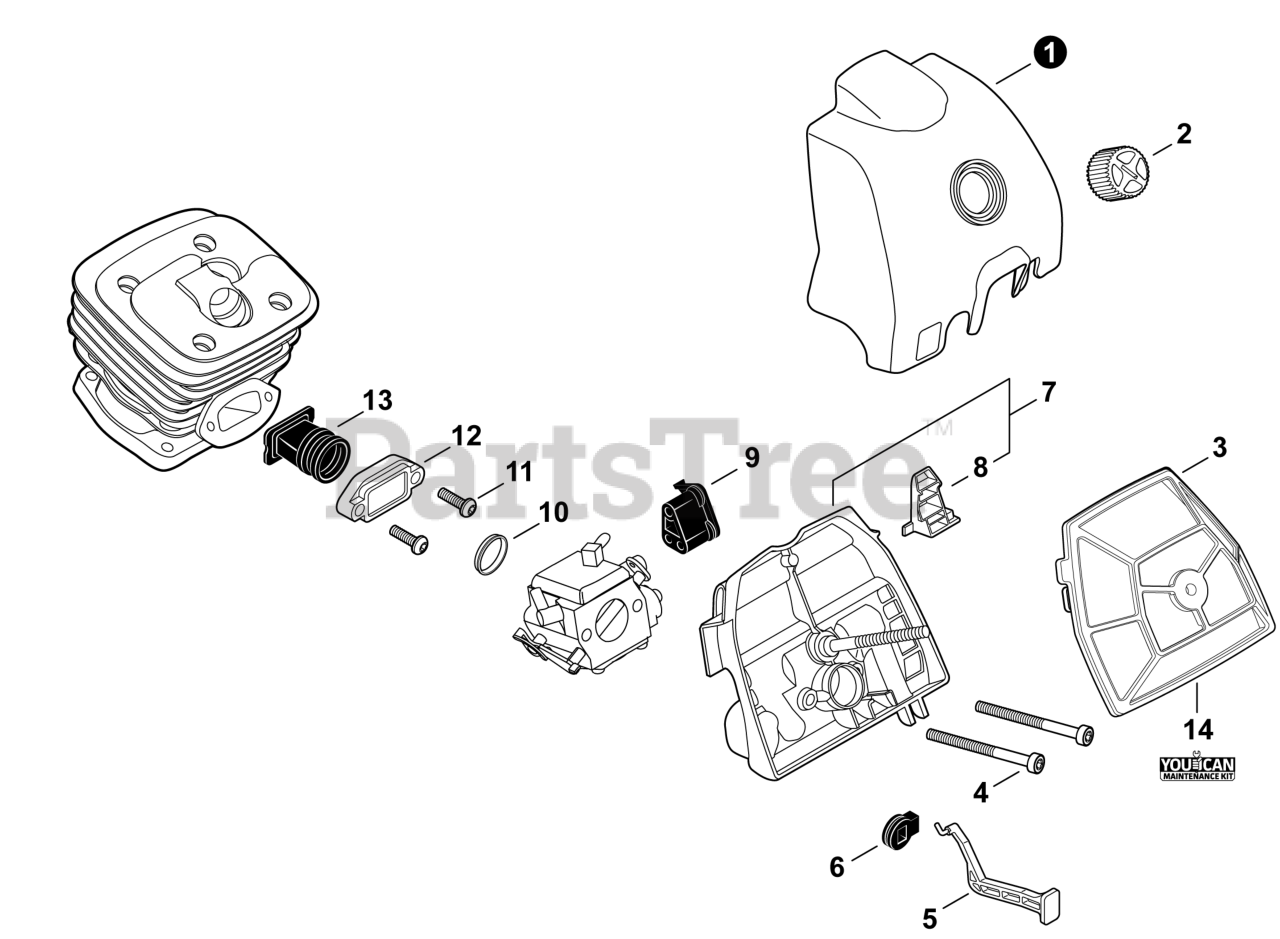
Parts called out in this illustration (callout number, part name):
1	COVER, AIR FILTER
2	KNOB, AIR FILTER COVER
3	FILTER ASSY, AIR
4	BOLT, TORX 5×50
5	ROD, CHOKE
6	GROMMET, CHOKE
7	CASE, AIR FILTER
8	SHUTTER, AIR
9	GROMMET, NEEDLE
10	COLLAR 18.6×20.4×4
11	BOLT, TORX 5×16
12	HOLDER, BELLOWS
13	BELLOWS, INTAKE
14	TUNE-UP KIT - YOUCANT
